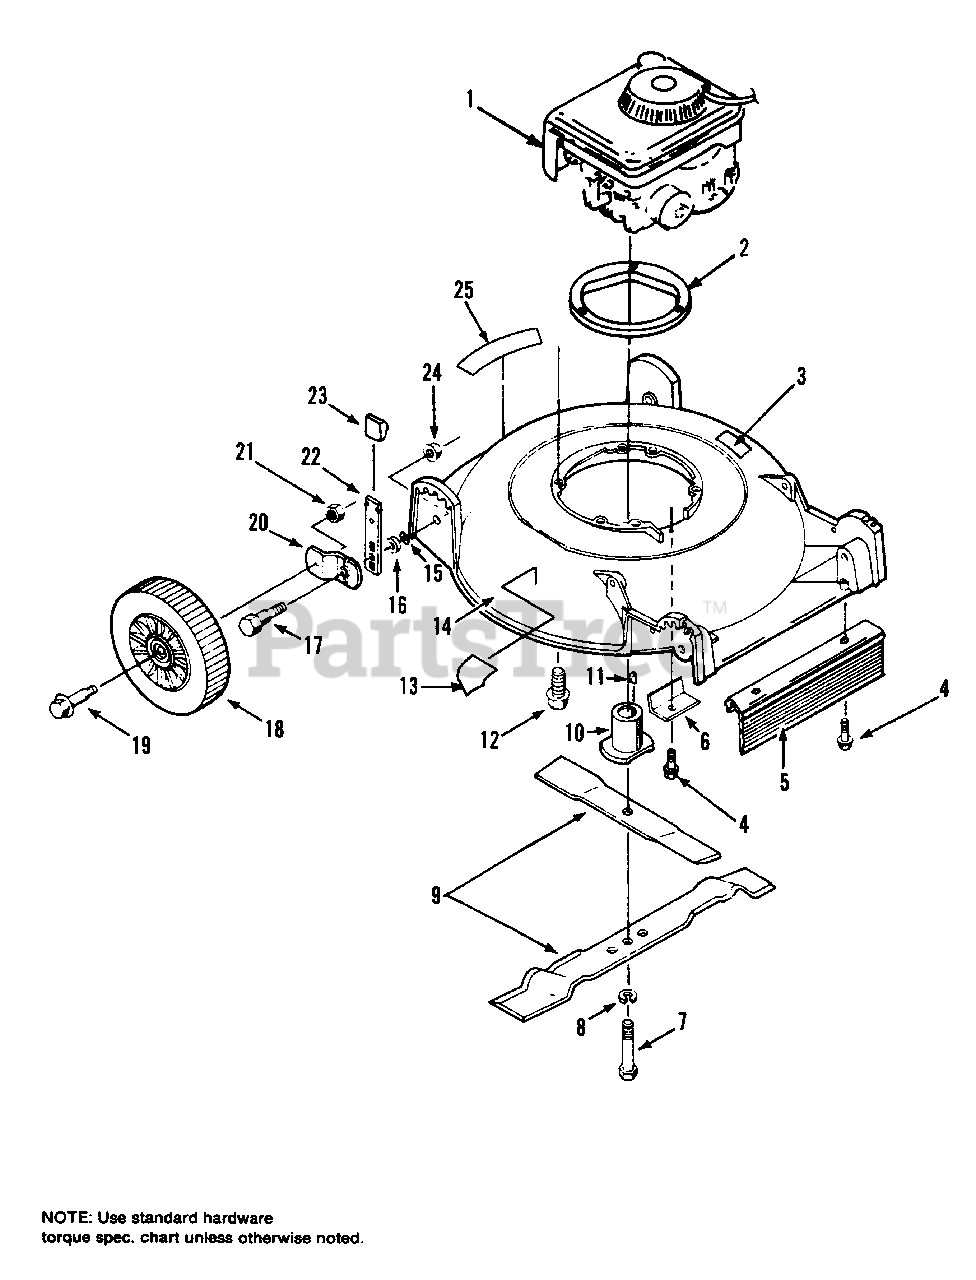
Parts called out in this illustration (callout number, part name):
1	ENGINE, 5.0 HP ENGINE, 4.0 HP Quantum
2	RING, Engine
3	DECAL, Warning
4	SCREW, Hex Hd., 1/4-20 x 3/4
5	SHIELD, Rear
6	COVER, Belt Opening (1691922 Only)
7	SCREW, 3/8-24 x 2
8	WASHER, Lock, 3/8
9	BLADE KIT
10	ADAPTER, Blade
11	KEY
12	SCREW, Hex Hd., 3/8-16 X 1-1/2
13	DECAL, Warning
14	DECK, 20" Push
14	DECK, 20" Self-Propelled
15	WASHER, 5/16-18 (Qty. 2 on 1691923)
16	SPACER, (Qty. 2 on 1691923)
17	BOLT, Hex Hd., 5/16-18 (Qty. 2 on 1691923)
18	WHEEL & TIRE ASSY., (Qty. 2 on 1691923)
19	BOLT, Axle, 3/8-16 (Qty. 2 on 1691923)
20	ARM, Wheel Adjustment (Qty. 2 on 1691923)
21	NUT, 3/8-16 (Qty. 2 on 1691923)
22	SPRING (Qty. 2 on 1691923)
23	KNOB (Qty. 2 on 1691923)
24	NUT, Flange, 5/16-18 (Qty. 2 on 1691923)
25	DECAL, 20" Simplicity
